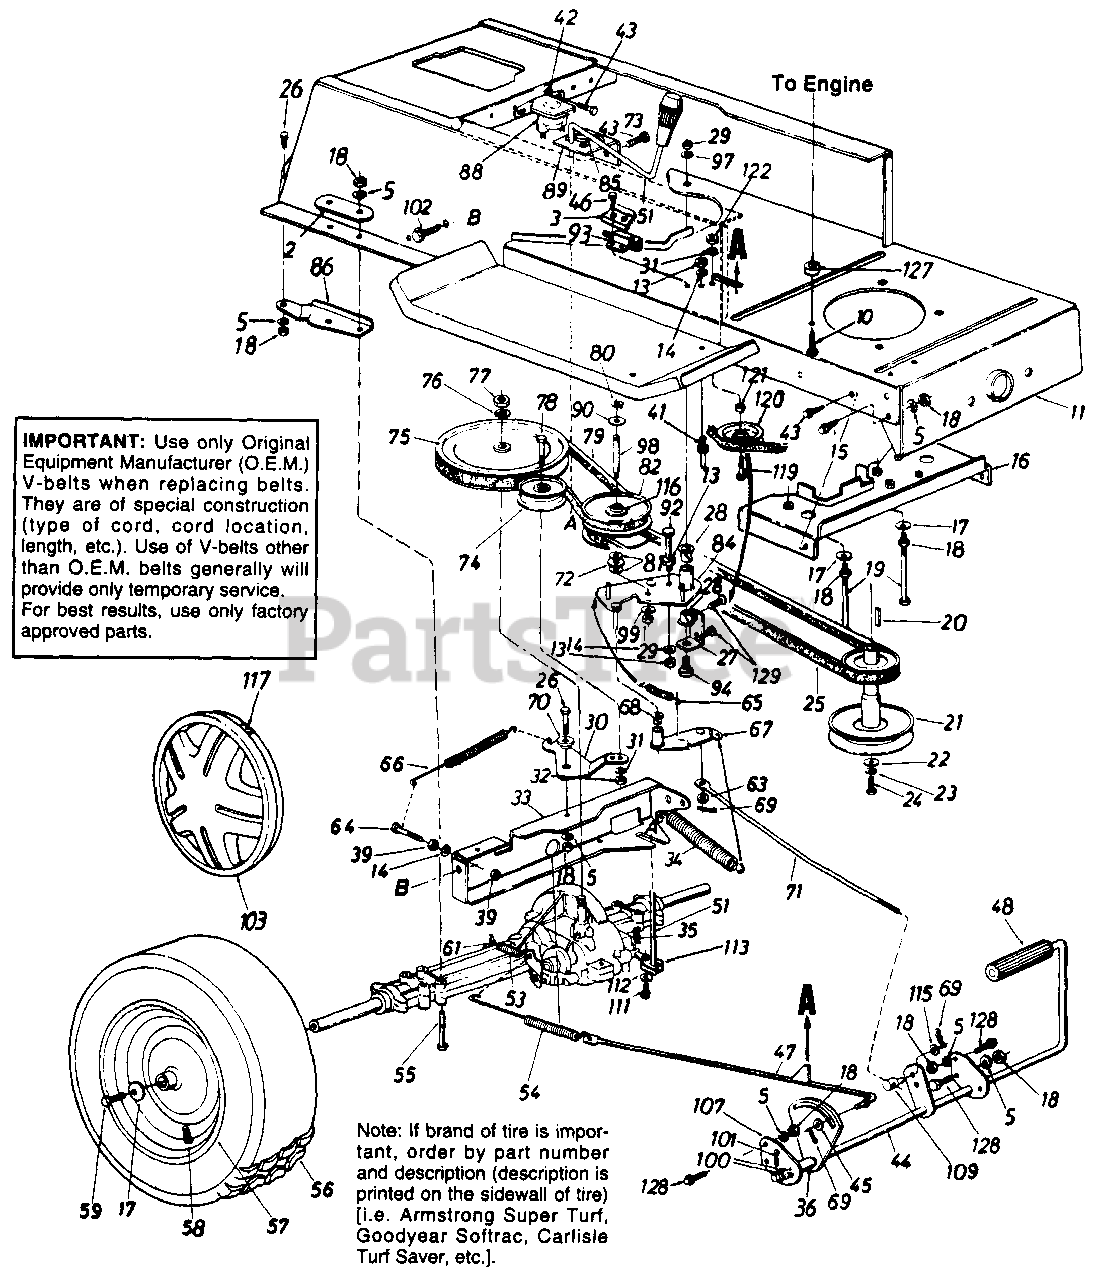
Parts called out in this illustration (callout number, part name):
3	Switch Plate
5	L-Wash. 5/16" I.D.
10	Hex Wash. Hd. AB-Tap Scr. 3/8-16 Thd.
11	Lower Frame Ass'y.
13	Hex Nut 1/4-20 Thd.
14	L-Wash. 1/4" I.D.
15	Hex TT-Tap Scr. 5/16-18 x .62"
16	Belt Guard Brkt. Ass'y.
17	Bell-Wash. .345" I.D. x .88"
18	Hex Nut 5/16-18 Thd.
19	Hex Bolt 5/16-18 x 4.0"
20	Sq. Key 1/4" x 1/4" x 2.00"
21	Engine Pulley
22	Fl-Wash. 7/16" I.D. x 1.25"
23	L-Wash. 7/16" I.D.
24	Hex Bolt 7/16-20 x 1.50" Lg.
25	Variable-Speed Belt
26	Hex Bolt 5/16-18 x .75" Lg.
27	Bearing Shaft Bracket Ass'y.
28	Flanged Cylinder Brg. 5/8" I.D. x .88" Lg.
29	Hex Nut 3/8-24 Thd.
31	L-Wash. 3/8" I.D.
32	Hex Nut 3/8-24 Thd.
35	Internal Cotter Pin
36	Spacer 63" I.D.
39	Hex Nut 1/4-28 Thd.
41	Belt Guard Pin
42	Ext. L-Wash. 1/4" I.D.
43	Hex Wash. Hd. S-Tap Scr. 1/4-20 x .50" Lg.
44	Clutch/Brake Pedal Ass'y.
45	Fl-Wash.
46	Truss Mach. Scr. B-Tap Scr. 10 x .5" Lg.
47	Brake Rod Ass'y.
48	Foot Pad
51	Shift Lever Ass'y.
53	Ext. Spring .38" O.D. x 2.5"
53	Ext. Spring .59" O.D. x 7.08"
55	Hex Bolt 5/16-18 x 2.75"
57	Wheel Rim Only
58	Air Valve
59	Hex Bolt 5/16-24 x .75" Lg.
61	Brake Return Spring Anchor
63	Fl-Wash. .34" I.D. x .68" O.D.
64	Hex Bolt 1/4-28 x 1.25" Lg.
65	Ext. Spring
66	Ext. Spring .62" O.D. x 6.12"
68	Flanged Bearing
69	Cotter Pin 3/32" Dia.
70	Shoulder Spacer .27" Lg.
71	Speed Control Link
72	Truss Bearing .56 Dia. x 1.25"
73	Shift Knob
74	Fl-Idler Pulley 3.25" x .75"
76	Bell-Wash. .56" I.D. x 1.125"
77	Hex Jam Nut 5/16-18 Thd.
78	Hex Bolt 3/8-24 x 1.75" Lg.
79	Variable Speed Belt
80	Snap Ring .56" Dia.
82	Variable Speed Pulley Ass'y. 5" O.D.
90	Teflon Washer .565" I.D.
92	Hex Bolt 1/4-20 x 3.5" Lg.
93	Safety Switch (Clutch)
94	Shld. Bolt 3/8-24 x 3.12" Lg.
97	Bell-Wash. .38" I.D. x .88"
98	Shaft .56" Dia. x 3.875" Lg.
99	Bell-Wash. .39" I.D. x 1.12"
100	Fl-Wash. .64" I.D. x .94"
101	Cotter Pin 1/8" Dia. x 1.25"
102	Hex Wash. Hd. Scr. 5/16-18 x .62" Lg.
103	Hub Cap
109	Ferrule
111	Hex Bolt 1/4-28 x .50" lg.
112	Bell-Wash. .265" I.D. x .75"
113	Shift Lever Link Ass'y.
115	Fl-Wash. .385" I.D. x .62"
116	Needle Brgs.
117	Spring Clip
119	Hex Bolt 3/8-16 x 1.25" Lg.
120	Ft-Idler w/Flanges 2.75" O.D.
121	Fl-Wash. .39" I.D. x 1.12" O.D
122	Hex Nut 3/8-16 Thd.
127	Spacer 5/16" I.D.
128	Hex Wash. TT-Tap Scr. 5/16-18 x .75" Lg.
129	Hex Wash. AB-Tap Scr. 5/16-18 x .75" Lg.
